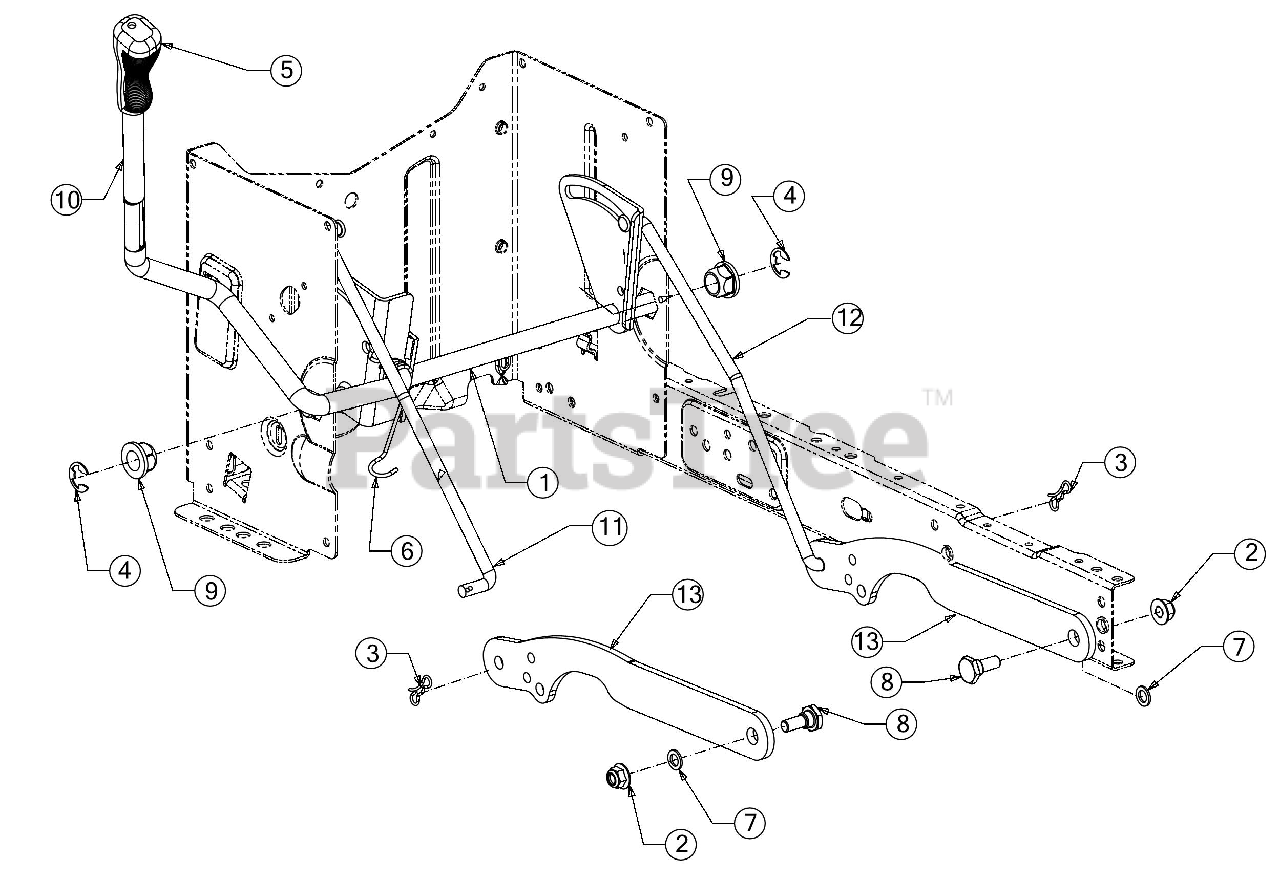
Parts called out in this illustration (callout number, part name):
1	LIFT SHAFT ASSEMBLY
3	PIN:COTTER
4	E-RING
6	TORSION SPRING
7	FLAT WASHER
8	SHOULDER SCREW
9	FLANGE BEARING
10	LIFT HANDLE
11	LIFT ROD (RH)
12	LIFT ROD (LH)
